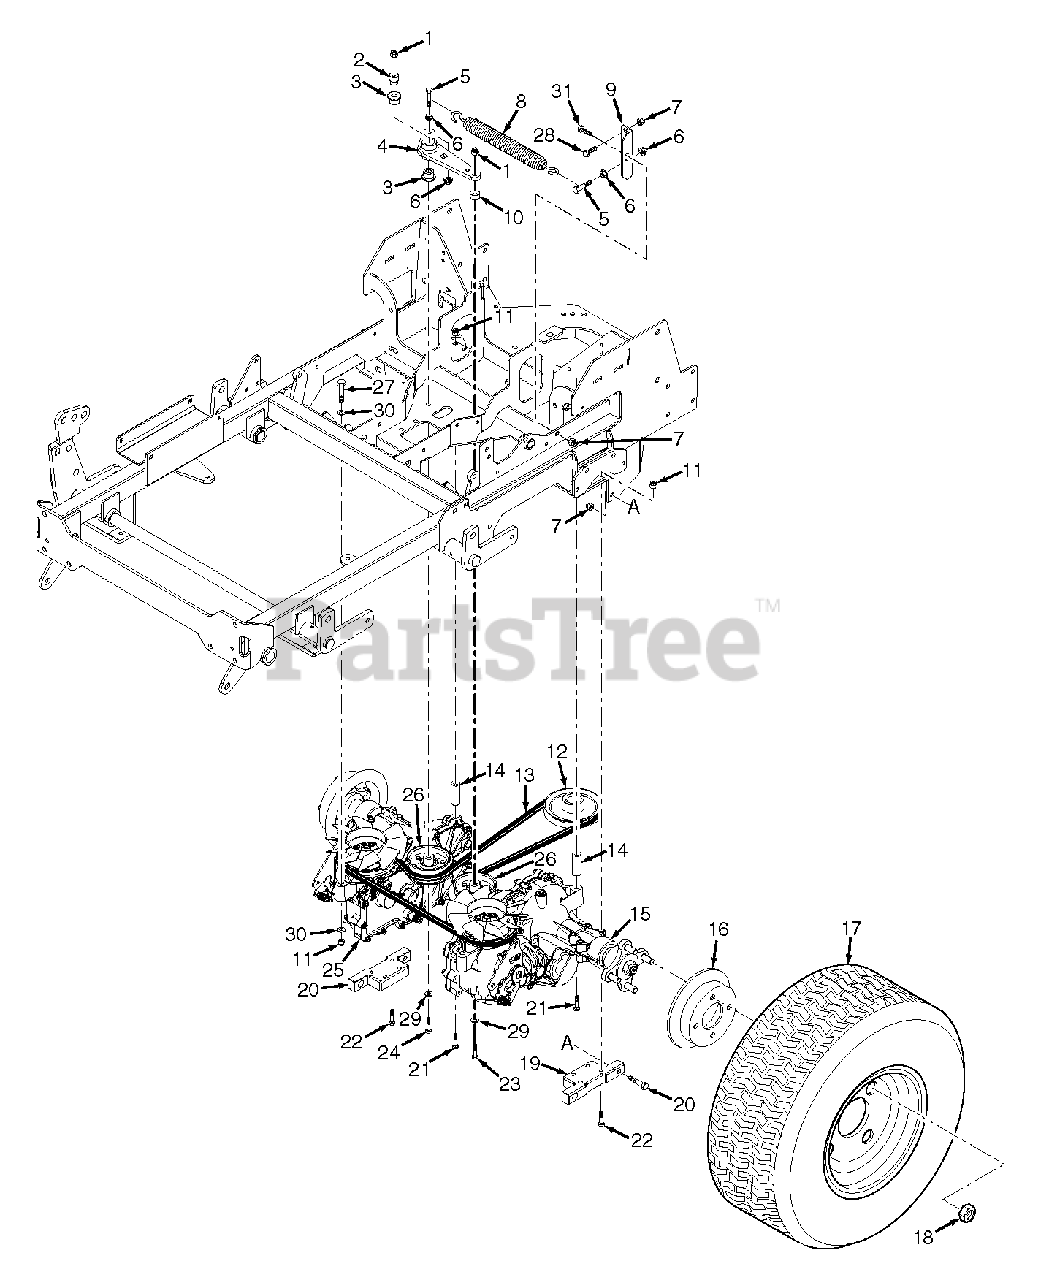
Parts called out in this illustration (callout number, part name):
1	Nut, Elastic Stop 3/8-16
2	Shaft, Pivot Idler Arm
3	Bearing
4	Idler Arm Assembly
5	Bolt, Hex Head 3/8-16 x 1-1/2"
6	Nut, Serrated Flange 3/8-16
7	Nut, Elastic Stop 3/8-16
8	Spring, Pump Drive
9	Anchor Bracket, Pump Spring
10	Spacer
11	Nut, Elastic Stop 5/16-18
12	Pulley, 5" Dia. - 1.125" Bore
13	Belt, Pump Drive
14	Spacer, Axle
15	Transaxle, LH
16	Spacer, Axle
17	Wheel Assembly, 23 x 9.5-12 (48)
17	Rim (48)
17	Tire, 23 x 9.5-12
17	Wheel Assembly, 23 x 9.5-12 (52)
17	Rim (52)
18	Wheel Nut, 1/2-20
19	Mount, Pusharm
20	Bolt, Hex Head 5/8-11 x 2-1/2"
21	Bolt, Hex Head 5/16-18 x 4-3/4"
22	Bolt, Hex Head 5/16-18 x 4"
23	Bolt, Hex Head 3/8-16 x 3-1/4"
24	Bolt, Hex Head 3/8-16 x 4-1/4"
25	Transaxle, RH
26	Pulley, 3-1/2" Idler
27	Bolt, Hex Head 5/16-18 x 2-1/4"
28	Bolt, Hex Head 3/8-16 x 1"
29	Flatwasher, 3/8-.391 x .938 x .105 HD
30	Flatwasher, 5/16-.375 x .875 x .083
31	Bolt, Hex Head 3/8-16 x 1-1/4"
